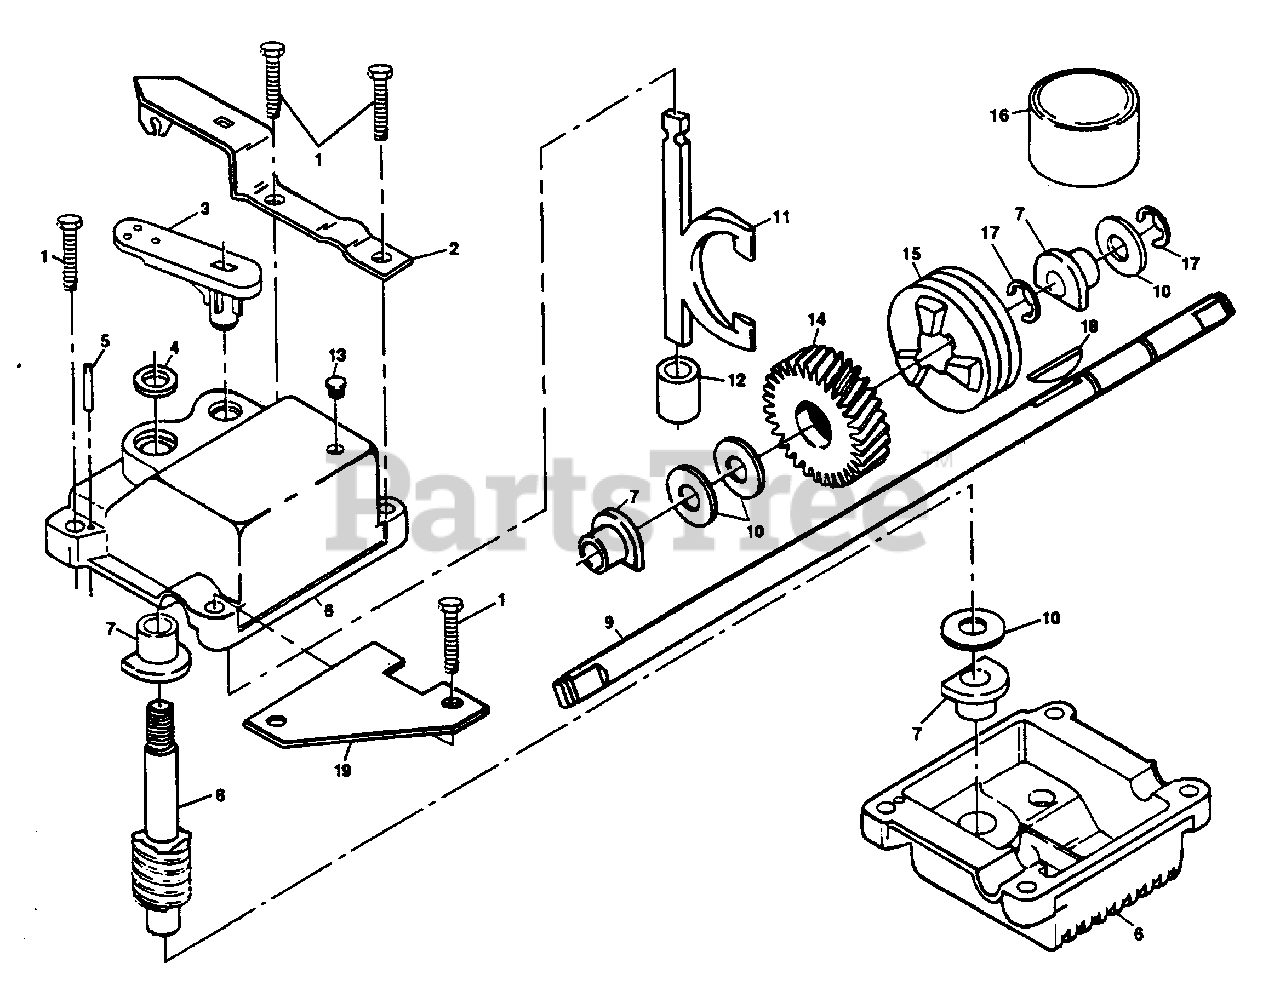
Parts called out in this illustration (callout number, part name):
1	Tapping Screw 1/4-20 x 1-1/4 (AYP part number)
2	Engagement Bracket (AYP part number)
3	Shifter (AYP part number)
5	Grooved Pin 1/8 x 5/8 (AYP part number)
6	Gear Case Halves Kit (Inc.4, 5, 7) (AYP part number)
7	Bearing (AYP part number)
8	Worm Shaft (AYP part number)
9	Drive Shaft (AYP part number)
10	Hardened Washer (AYP part number)
11	Clutch Yoke (AYP part number)
12	Bushing (AYP part number)
13	Plug (AYP part number)
14	Helical Gear (AYP part number)
15	Clutch Jaw (AYP part number)
16	Grease (AYP part number)
18	Hi-Pro Key (AYP part number)
19	Spring Bracket (AYP part number)
